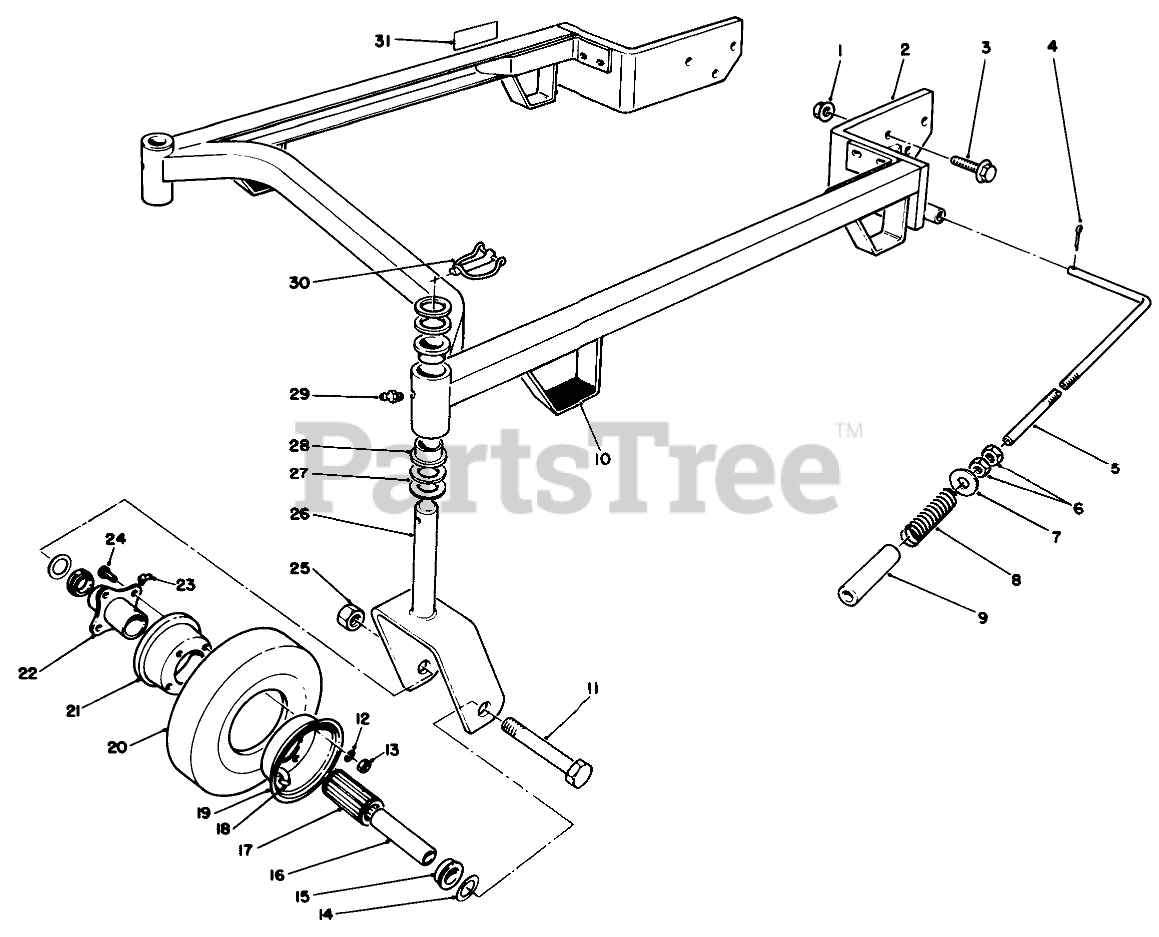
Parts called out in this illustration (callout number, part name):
1	NUT-HF
2	Suspension Frame (Incl. Ref. #28)
3	SCREW-HHF
4	PIN-COTTER
5	ADJUSTING SHAFT
6	NUT-JAM
7	WASHER
8	SPRING-COMPRESSION
9	SLEEVE-TUBE, 36 INCH
10	Pad-Rubber
11	SCREW-HH
12	WASHER-LOCK
13	NUT-HEX
14	SPACER-WHEEL
15	RETAINER
16	Bushing-Spanner
17	BEARING-ROLLER
19	WHEEL HALF-MALE
20	TIRE-8 Inch (4-PLY)
21	WHEEL HALF-FEMALE
22	HUB-CENTERED
23	FITTING-GREASE
24	WHEEL BOLT
25	NUT-LOCK
26	FORK-Castor
27	WASHER-THRUST
28	Bushing
29	FITTING-GREASE
30	PIN-LYNCH
31	DECAL-CAUTION, DEFLECTOR
